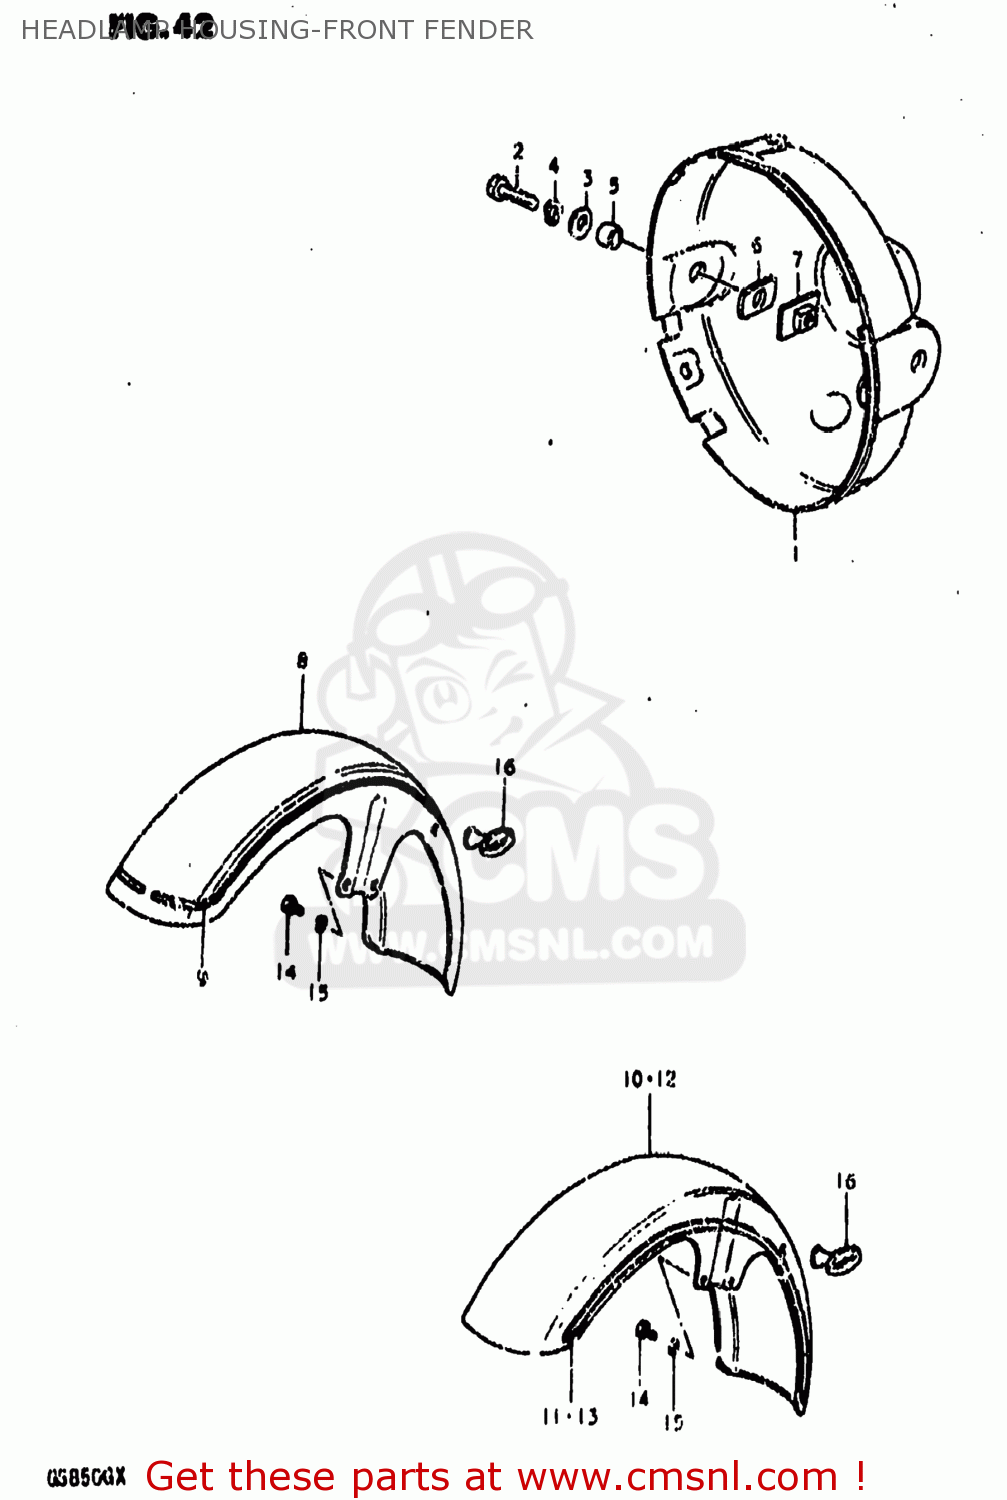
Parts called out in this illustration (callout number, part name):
1	HOUSING,HEADLAMP(BLACK)
2	BOLT
3	WASHER
4	LOCK WASHER
5	BOLT 8X125
6	CUSHION
7	PLATE,HEADLAMP HOUSING
8	FENDER,FRONT
9	TAPE,FRONT FENDER STRIPE
10	FENDER,FRONT
11	TAPE,FRONT FENDER
12	FENDER,FRONT
13	TAPE SET,FRONT FENDER
14	BOLT
15	LOCK WASHER
16	GUIDE,CABLE
